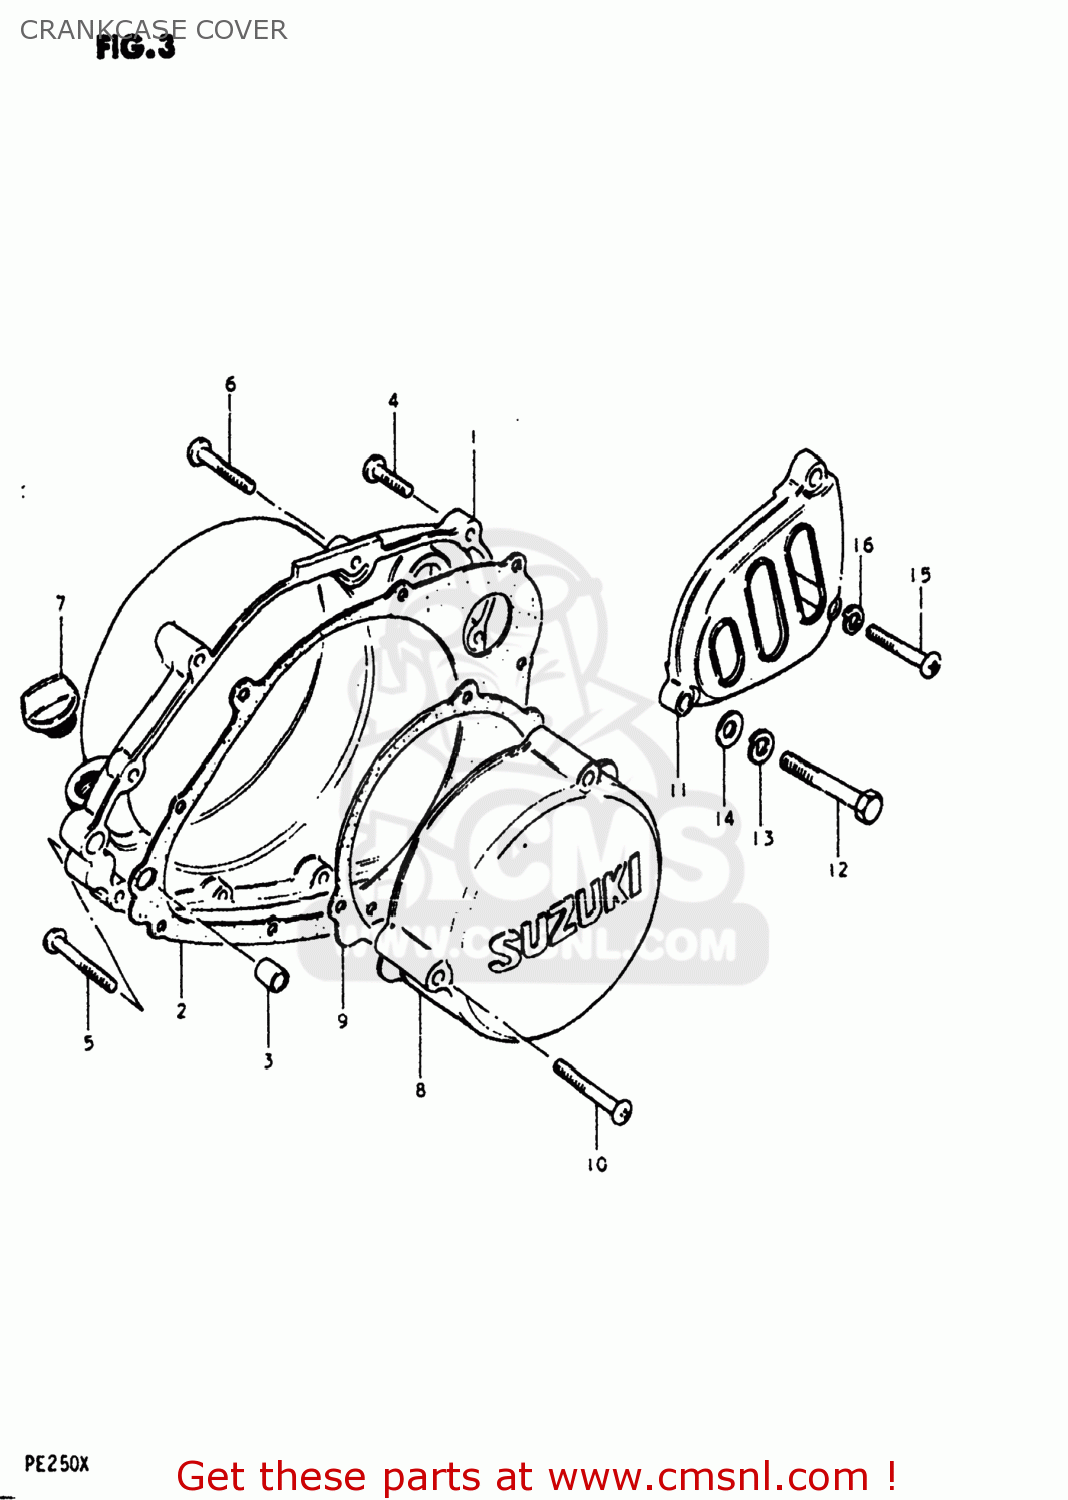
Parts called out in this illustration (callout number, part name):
1	COVER,CLUTCH
2	GASKET,CLUTCH COVER (MCA)
3	PIN
4	SCREW
5	SCREW (6X45)
6	SCREW 6X30
7	PLUG,OIL FILTER
8	COVER,MAGNETO
9	GASKET,MAGNETO COVER (NAS)
10	SCREW
11	COVER,ENGINE SPROCKET
12	BOLT 8X55
13	LOCK WASHER
14	WASHER 6MM
15	SCREW
16	LOCK WASHER
